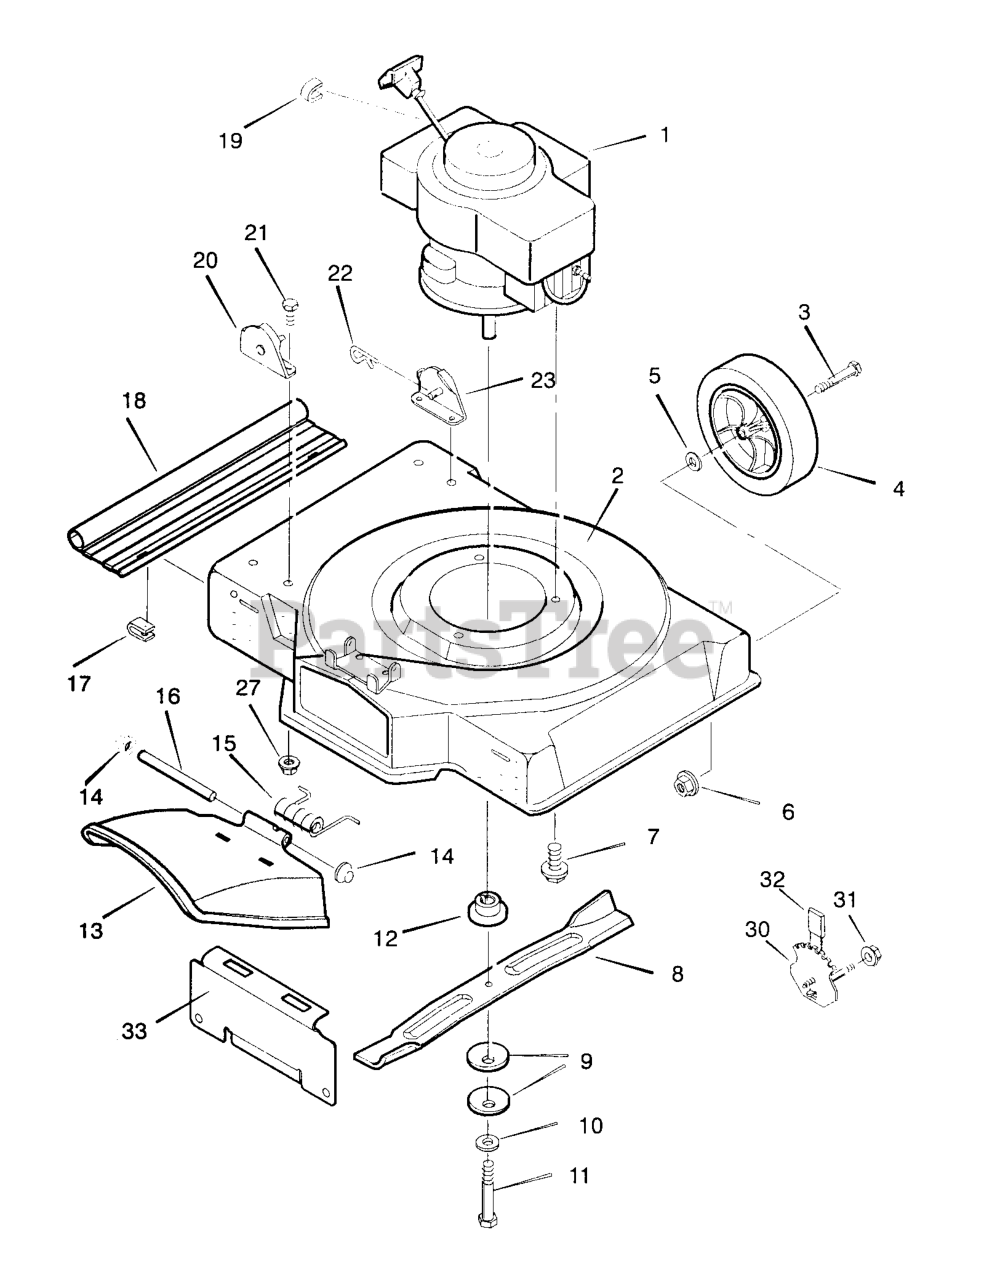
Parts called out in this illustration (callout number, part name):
1	Engine *
2	Housing
3	Bolt, Axle
4	Wheel and Tire *
6	Locknut, Flange
7	Bolt, Engine
9	Washer, Belleville
11	Bolt, Hex
12	Adapter, Blade
13	Deflector, Chute
14	Push- On Cap
16	Pin, Pivot
17	Retainer
18	Deflector, Rear
19	Stop, Rope
20	Bracket, Right Handle
22	Pin, Hair
23	Bracket, Left Handle
27	Nut
30	Adjuster, Height
31	Locknut, Flange
